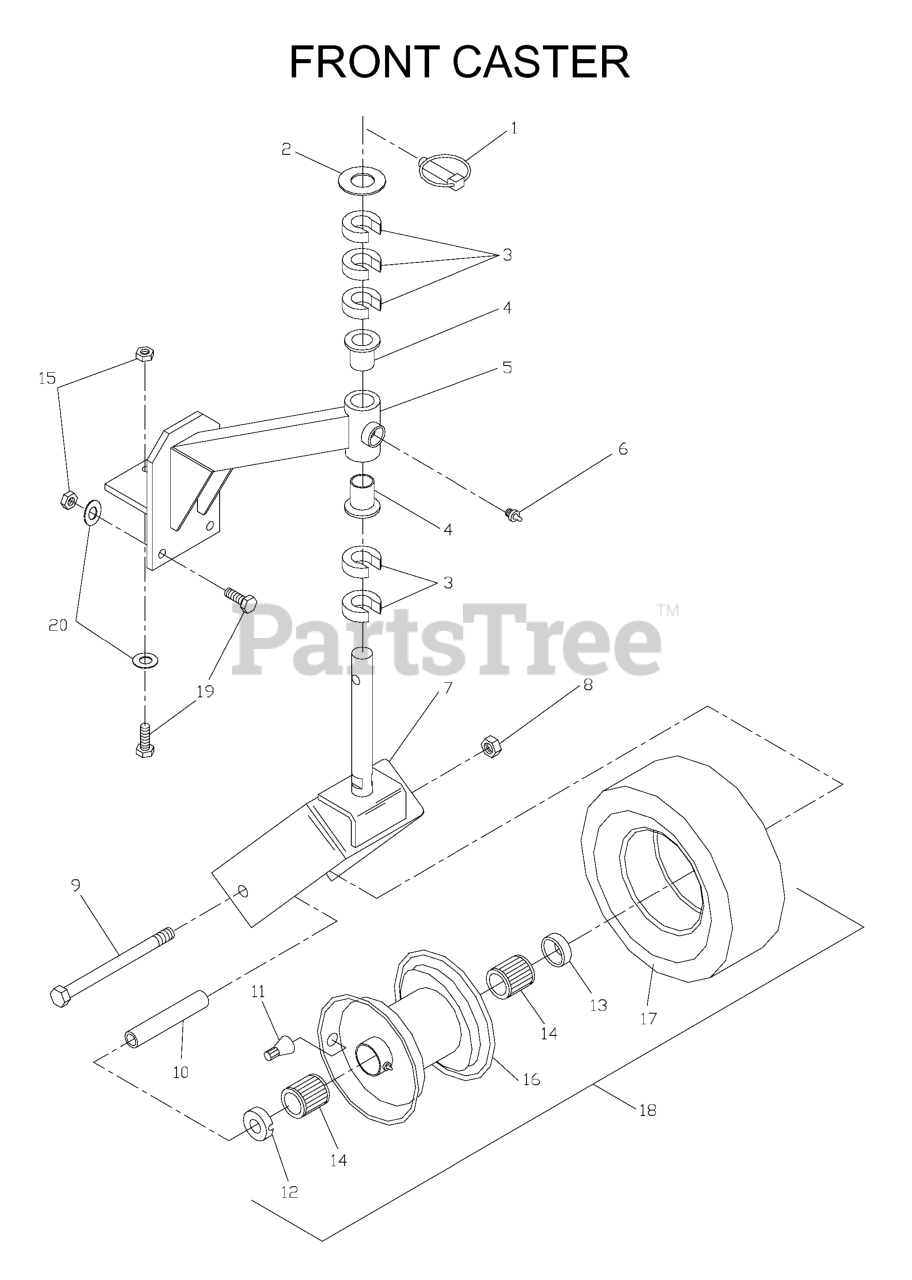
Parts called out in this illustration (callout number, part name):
1	LYNCH PIN 7/16
2	MACHINE BUSHING
4	BUSHING, FLANGED
5	CASTER ARM W/BUSHING
6	ZERK 1/8 NPT
7	CASTER YOKE
8	NUT 1/2-13 HEX NYLOC ZD
9	HCS 1/2C X 5 1/2
11	VALVE STEM TR-412
12	ENDCAP, NOTCHED
13	ENDCAP
14	ROLLER BEARING
15	NUT 3/8C CENTERBLOCK
17	TIRE 9 X 3.5 - 4
18	TIRE/WHEEL.CASTER.9X3.5-4.SMOO
19	HCS 3/8-16X1.GRD.5.ZD
20	WASHER 3/8 FLAT
21	WHEEL CAST. ASM KIT
